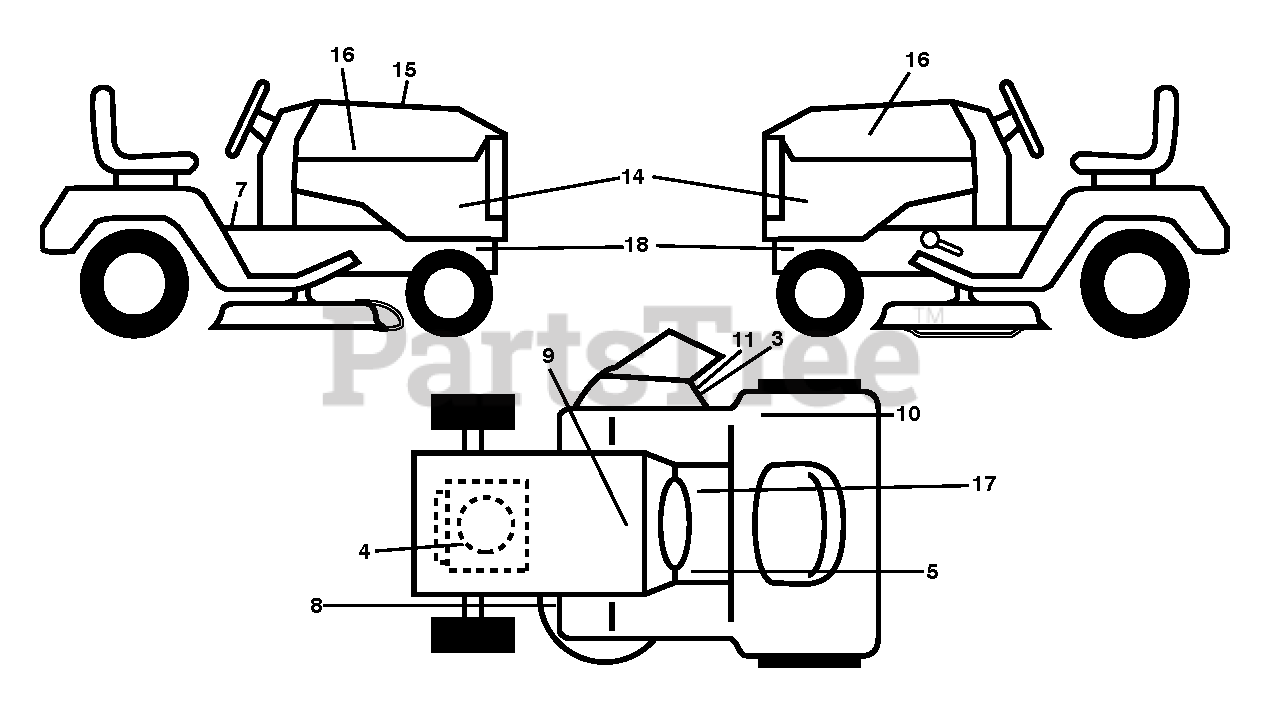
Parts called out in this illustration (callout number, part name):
3	DECAL.DFLCTR.WARNNG.CTFNGR.SYM
4	DECAL.ENGINE.WARNING
5	DECAL.FNDR.SDLE.BRAKE.CLUTCH.6
7	DECAL.READ.OWN.MAN.SYMBOL.LT
8	DECAL.MOWER.SCH.48/54.PREM
9	DECAL BTRY SYMBOLS
10	DECAL.FENDER.105DB/CE.
11	DECAL.CUTFINGER.CE.02
15	DECAL.RPL.KAW.FS.TGW.48.HG700
16	DECAL.BADGE.170MM.TEXTLOGO.
17	DECAL.PARKING.BRAKE.SADDLE.LT
18	DECAL.CHASSIS.HOT.MUFFLER
